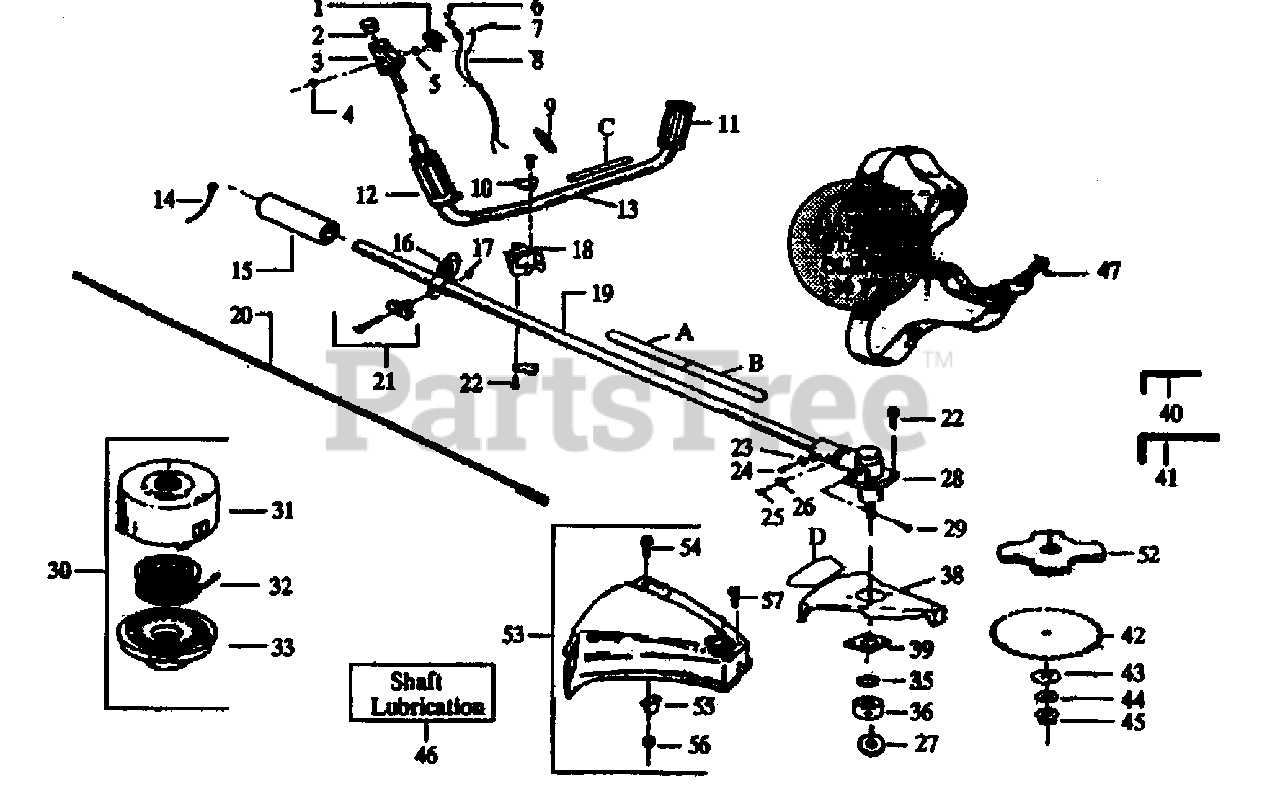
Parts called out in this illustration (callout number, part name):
1	Kill Switch Bracket
2	Handlebar Cap
3	Throttle Lever Ass'y. w/ Lock
6	Nut
8	Wire Harness Ass'y
9	Terminal Lock
10	Handlebar Bracket
11	Handlebar Grip
12	Handguard Grip
15	Drive Shaft Pad
16	Clamp Harness Ass'y.
18	Handlebar Clamp
19	Drive Shaft Housing
20	Drive Shaft
21	"T" Handle Ass'y.
22	Screw
23	Lockwasher
26	Lockwasher
27	Grass Washer
28	Gear Box Ass'y.
30	Cutting Head Ass'y.
31	Hub Ass'y.
32	Spool w/Line
39	Shield Retention Plate
40	Hex Wrench (5/32)
41	Hex Wrench (9/16)
42	Brush Blade -- 8"
44	Washer
46	Shaft Lubrication
47	Shoulder Strap
52	Weed Blade
53	Shield Kit Ass'y.
55	Line Limiter
56	Locknut
57	Screw
A	Decal-Shaft Warning (Upper)
B	Decal-Shaft Warning (Lower)
C	Decal-Handlebar Warning
D	Decal-Blade Direction
